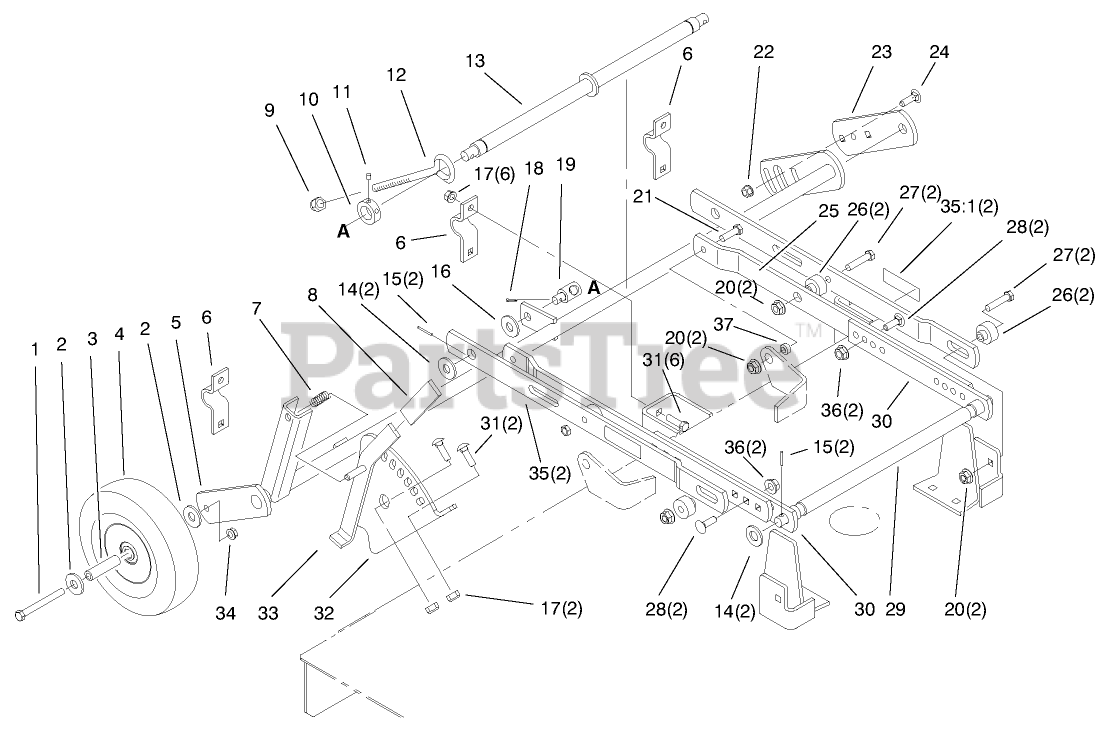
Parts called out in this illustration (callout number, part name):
1	SCREW-HH
2	WASHER-FLAT
3	SPACER
5	SUPPORT-WHEEL, 60"
7	SPRING-COMPRESSION
9	NUT-LOCK, NI
10	COLLAR
11	SCREW-SET, HSH
12	ROD-ADJUSTMENT, LEVEL
13	SHAFT ASM-LEVELER
14	WASHER-FLAT
15	PIN-ROLL, SPIROL
16	WASHER-FLAT
17	NUT-LOCK, NI
18	PIN-COTTER
19	TRUNNION
21	SCREW-HH
22	NUT-FLANGE
23	SUPPORT-GAGE WHEEL
24	BOLT-CARR
25	DRAFTBAR
26	SPACER
27	SCREW-HH
28	SCREW-CARR
31	BOLT-CARR
32	QUADRANT-DECK
33	LEVER-HOC
35	LH LEVELER ASM *B
35	RH LEVELER ASM *B
35:1	DECAL-WARNING
36	NUT-LOCK, CONE
37	SPACER
